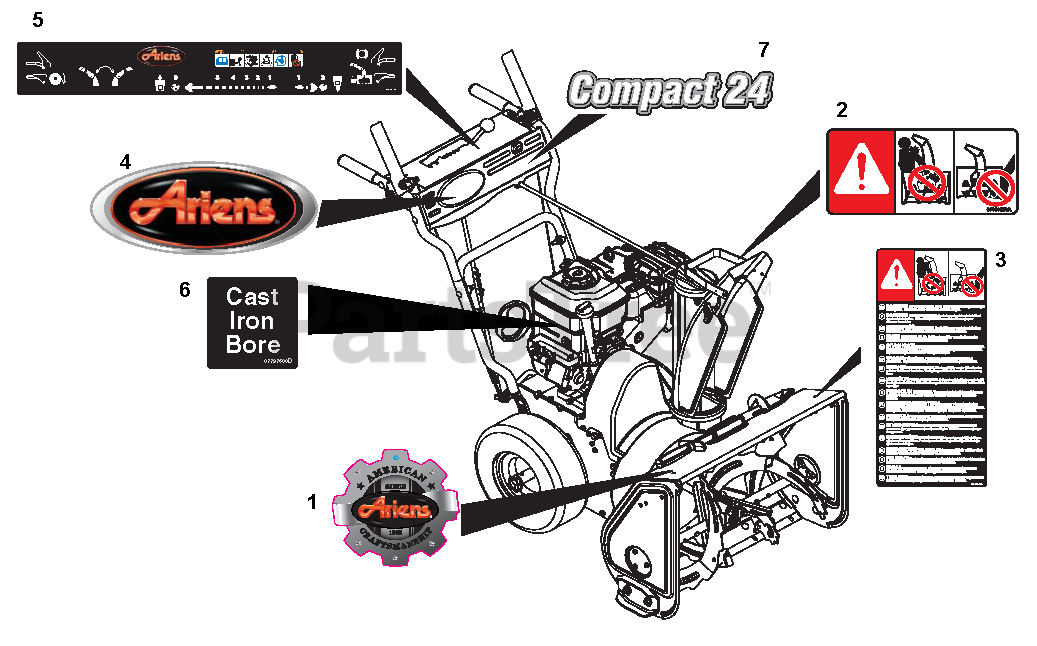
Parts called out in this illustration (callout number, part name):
1	Decal, Ariens Heritage
2	DECAL, DANGER
3	DECAL, DANGER - ROTATING PARTS
4	DECAL, ARIENS JEWEL
5	DECAL, CONTROL, COMPACT/DELUXE
5	DECAL, CONTROL, COMPACT REMOTE
6	DECAL - CAST IRON BORE
7	DECAL, ST20 COMPACT
7	DECAL, COMPACT 22
7	DECAL, COMPACT 24
7	DECAL, COMPACT 26
